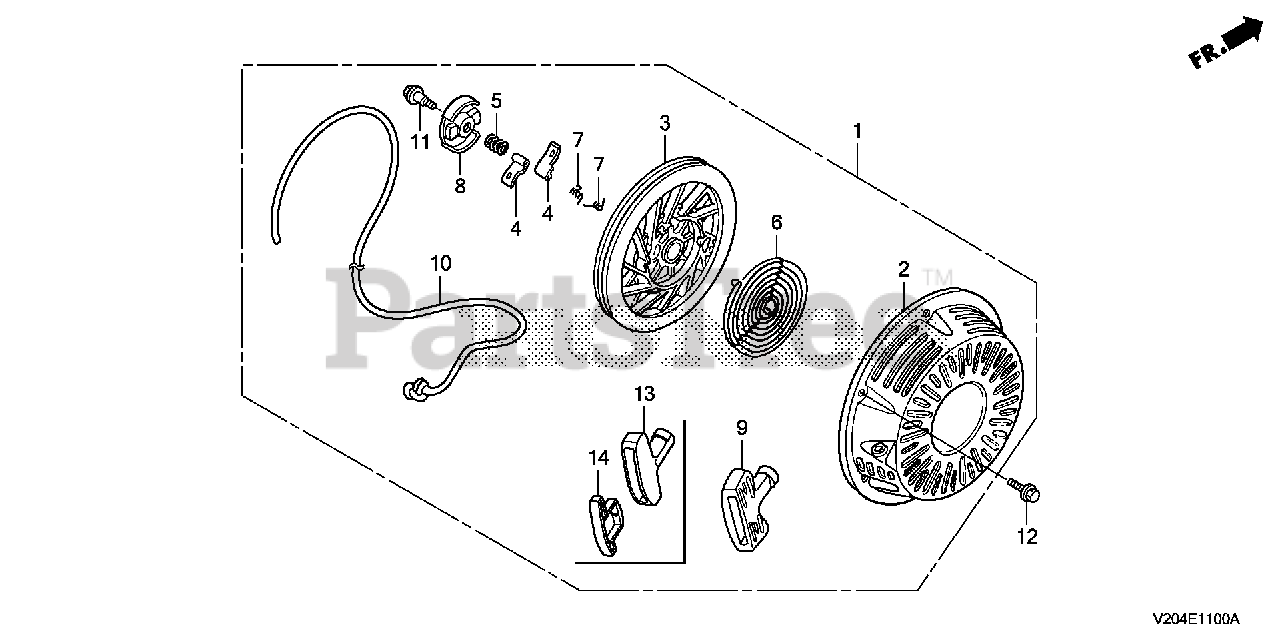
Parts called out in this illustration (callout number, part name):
1	STARTER ASSY., RECOIL *R280* (POWER RED)
2	CASE, RECOIL STARTER *R280* (POWER RED)
3	PULLEY, RECOIL STARTER
4	RATCHET, STARTER
5	SPRING, FRICTION
6	SPRING, STARTER RETURN
7	SPRING, RATCHET
8	RETAINER, SPRING
9	GRIP, STARTER
10	ROPE, RECOIL STARTER (#5X55")
11	SCREW, CENTER
12	BOLT, FLANGE (6X10)
